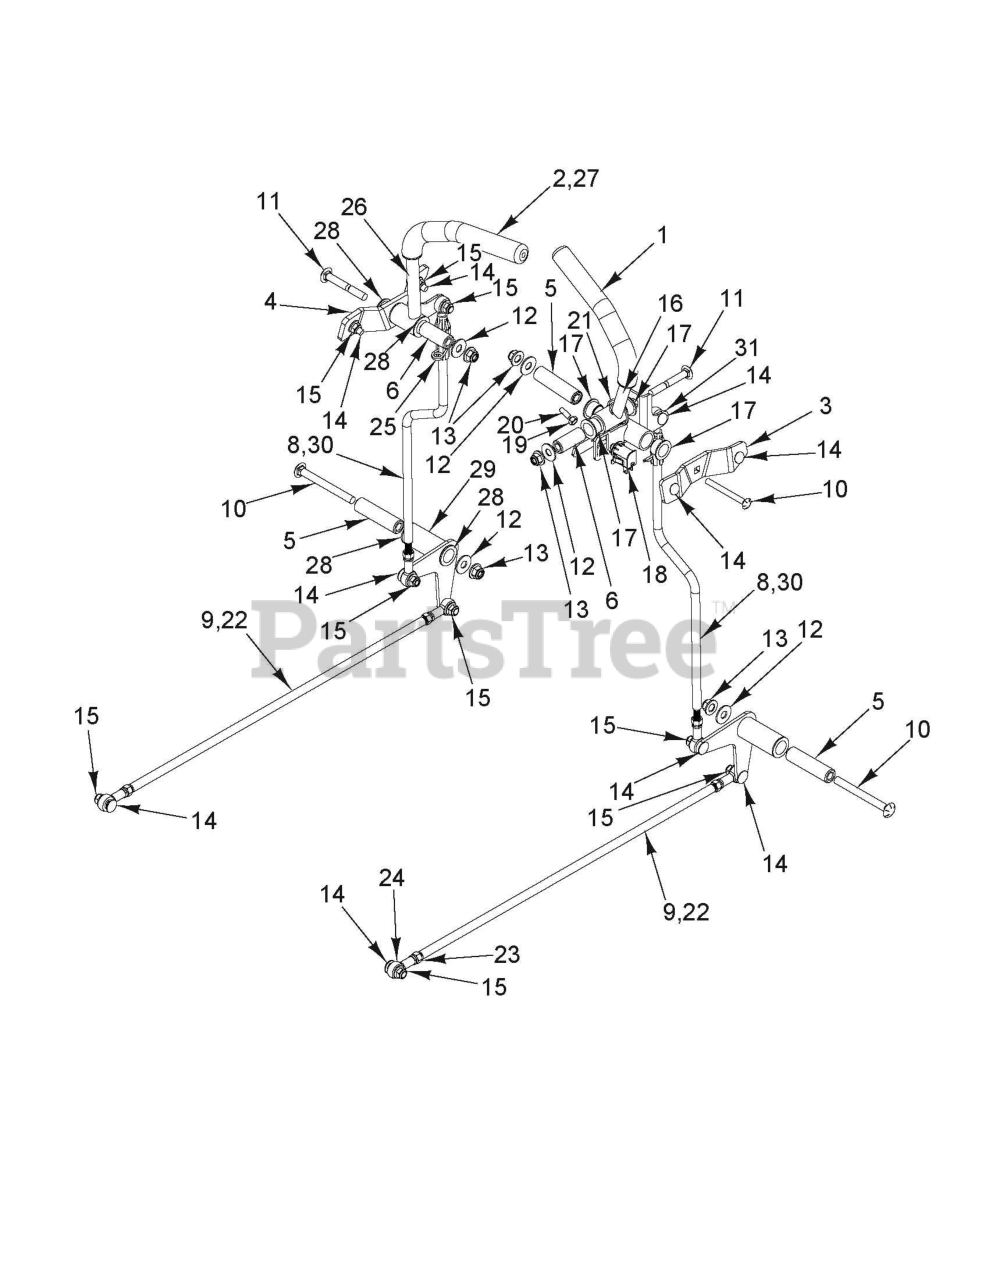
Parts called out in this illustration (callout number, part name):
1	KIT.SVC.ASM.LEVER.CNTRL.LH
2	KIT.SVC.ASM.LEVER.RH
3	BRACKET LH PIVOT; STAND ON E-D
4	BRACKET RH PIVOT; STAND ON E-D
5	SPACER BELLCRANK PIVOT LONG
6	Pivots
8	Controls
9	LINKAGE CONTROL LINKAGE ASSY;
10	Screws
11	BOLT
12	Washers
13	GSPW Nuts
14	Bolts
15	NUT HEXAGON FLANGE 5/16-18 ST
16	LEVER ASSY WELDMENT; OPS E-DIP
17	BEARING, FLANGE
18	SWITCH.SNAPMOUNT.NC
19	NUT
20	SCREW ASME B18.3, HEXAGON SOCK
21	SPRING TORSION; OPS
22	Links
23	Hardware
24	JOINT.HEIM.FEML.5/16.RH.THREAD
25	CLIP.RETAINER.CONTROLS
26	HANDLE ASSY HANDLE WELDMENT, R
27	GRIP 1/2 DIAM; .215 THICK; 8.5
28	BEARING, FLANGE
29	BELLCRANK WELDMENT; STAND ON C
30	Controls
31	BELLCRANK WELDMENT; CONTROLS;
